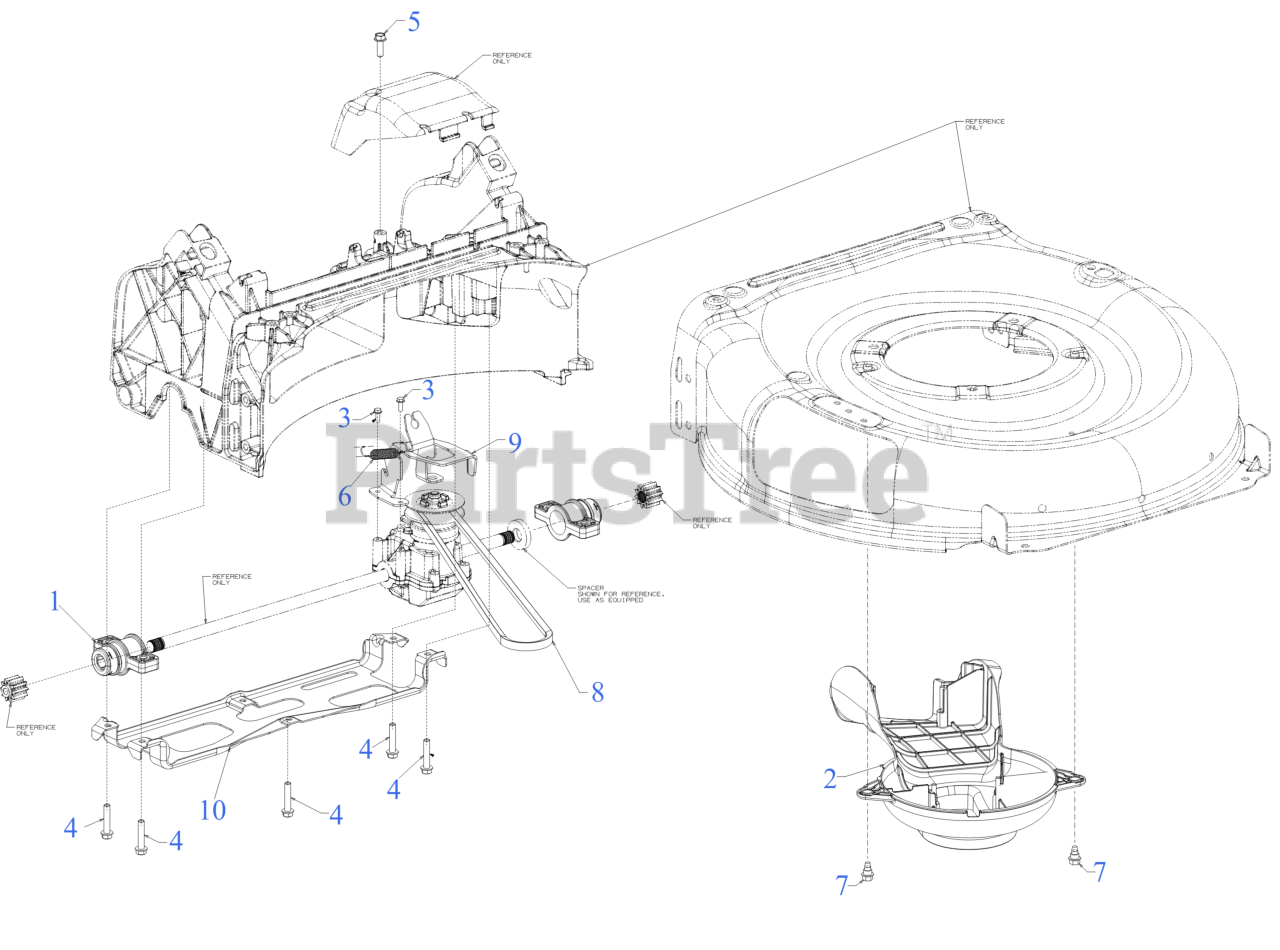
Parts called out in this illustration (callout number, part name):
1	BEARING ASSEMBLY
2	ENGINE BAFFLE ASSEMBLY
3	SCREW .159 x .43
4	SCREW 1/4-15 x 1.250
5	SCREW 1/4-15 x .750
6	EXTENSION SPRING
7	SHOULDER SCREW 1/4-20 x .50
8	V-BELT 31.25"
8	Genuine Factory Parts TRANSMISSION BELT
9	TRANSMISSION BRACKET
10	REAR CLIP SUPPORT BRACKET
